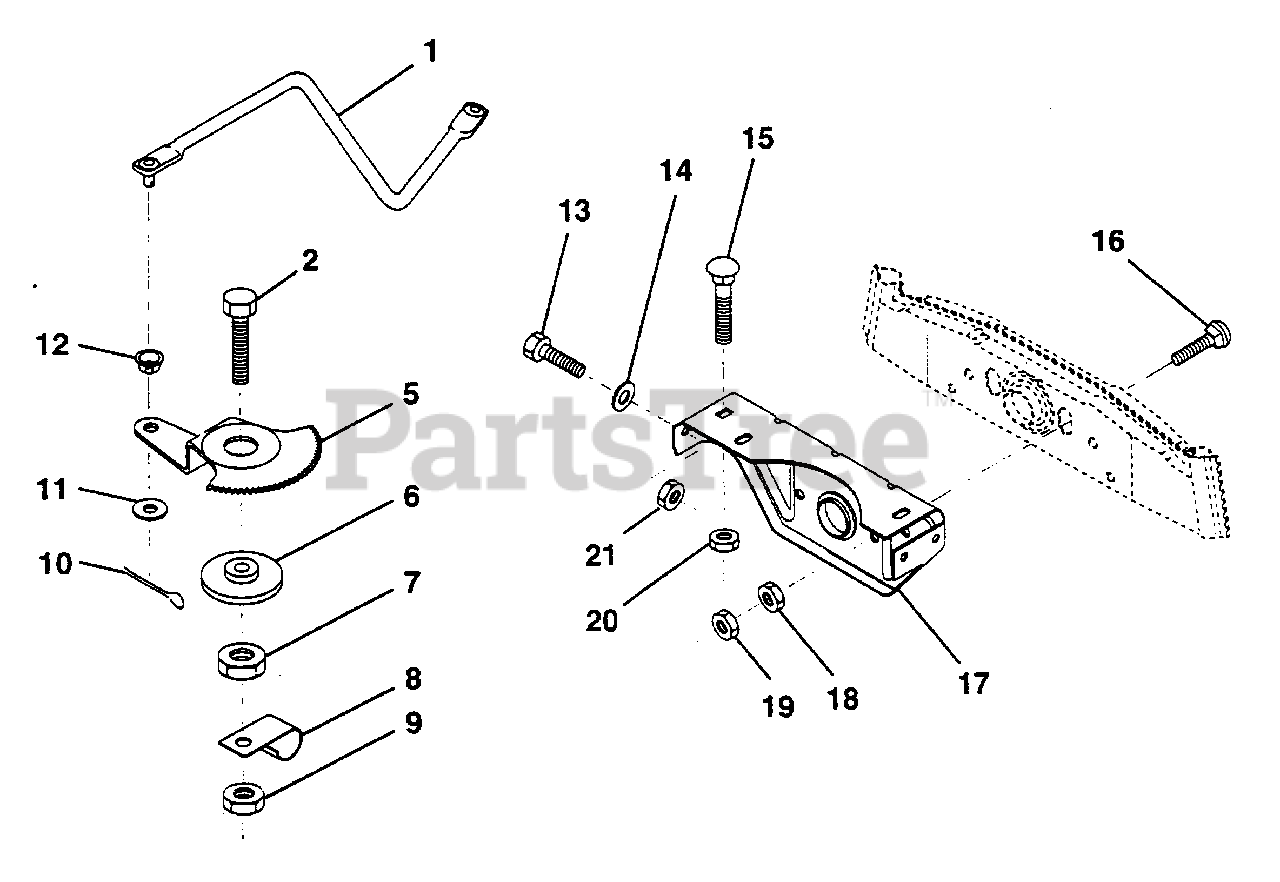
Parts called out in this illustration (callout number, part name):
1	Link, Drag (AYP part number)
2	Bolt, Fin Hex 1/2-13 x 1-3/4 (AYP part number)
5	Gear, Sector (AYP part number)
6	Bushing (AYP part number)
7	Nut, Heavy Hex Top Lock 1/2-13 UNC (AYP part number)
8	Clip, Insulated (AYP part number)
9	Nut, Crownlock 3/8-16 (AYP part number)
10	Pin, Cotter 1/8 x 3/4 (AYP part number)
11	Washer, 13/32 x 13/16 x 16 Ga. (AYP part number)
12	Bushing (AYP part number)
13	Bolt, Hex Hd. 5/16-18 UNC x 3/4 (AYP part number)
14	Washer 11/32 x 7/8 x 16 Ga. (AYP part number)
15	Bolt, Carriage 3/8-16 UNC x 3/4 (AYP part number)
16	Bolt, Carriage (AYP part number)
17	Support, Front Axle (AYP part number)
18	Nut, Fin Hex 3/8-16 UNC (AYP part number)
19	Nut, Centerlock 3/8-16 UNC (AYP part number)
20	Nut, Crownlock 3/8-16 UNC
21	Nut, Crownlock 5/16-18
